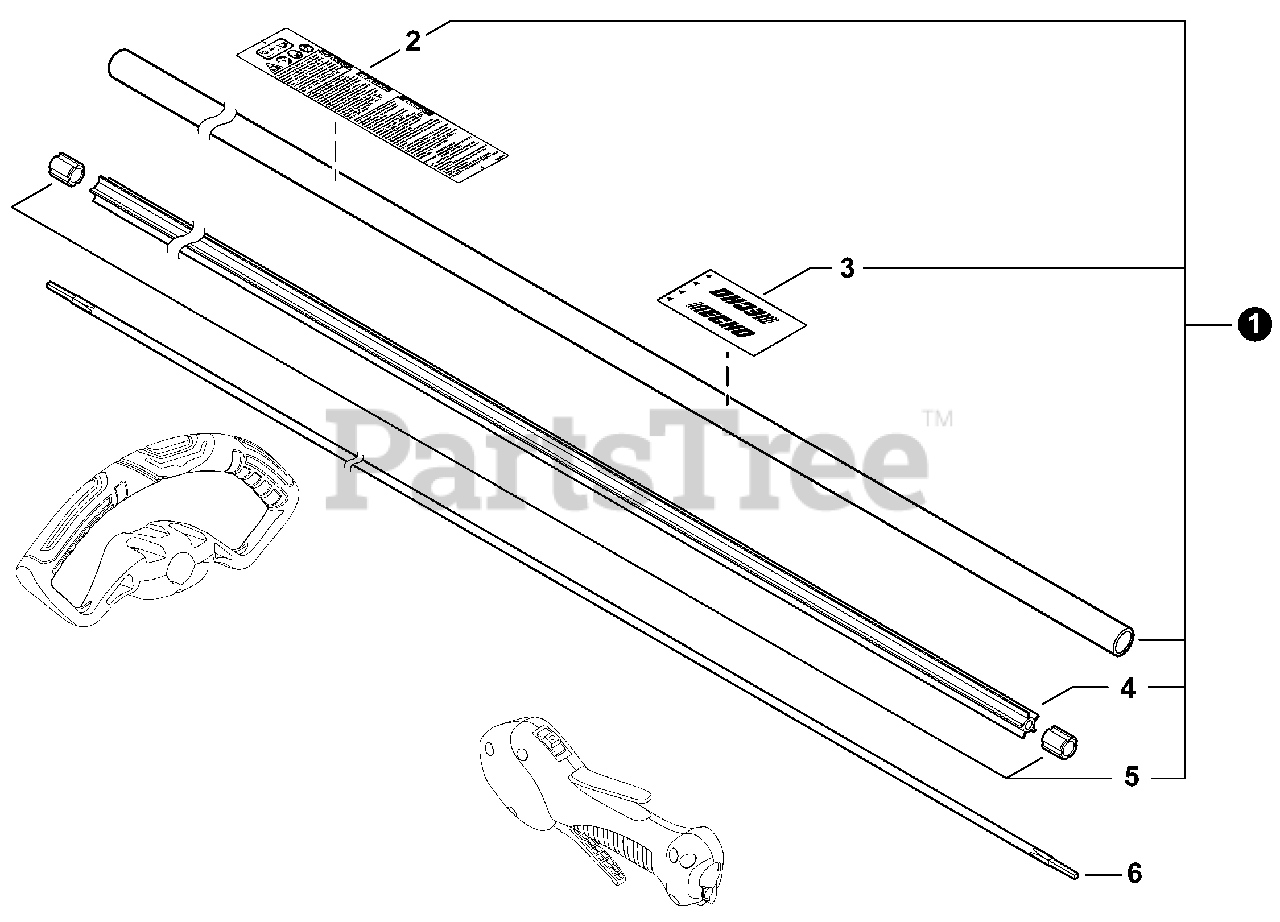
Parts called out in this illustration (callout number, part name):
1	MAIN PIPE ASSY
2	LABEL, CAUTION
3	LABEL, HANDLE LOCATION
4	LINER, FLEXIBLE 21.6×1420
6	DRIVESHAFT - FLEXIBLE
